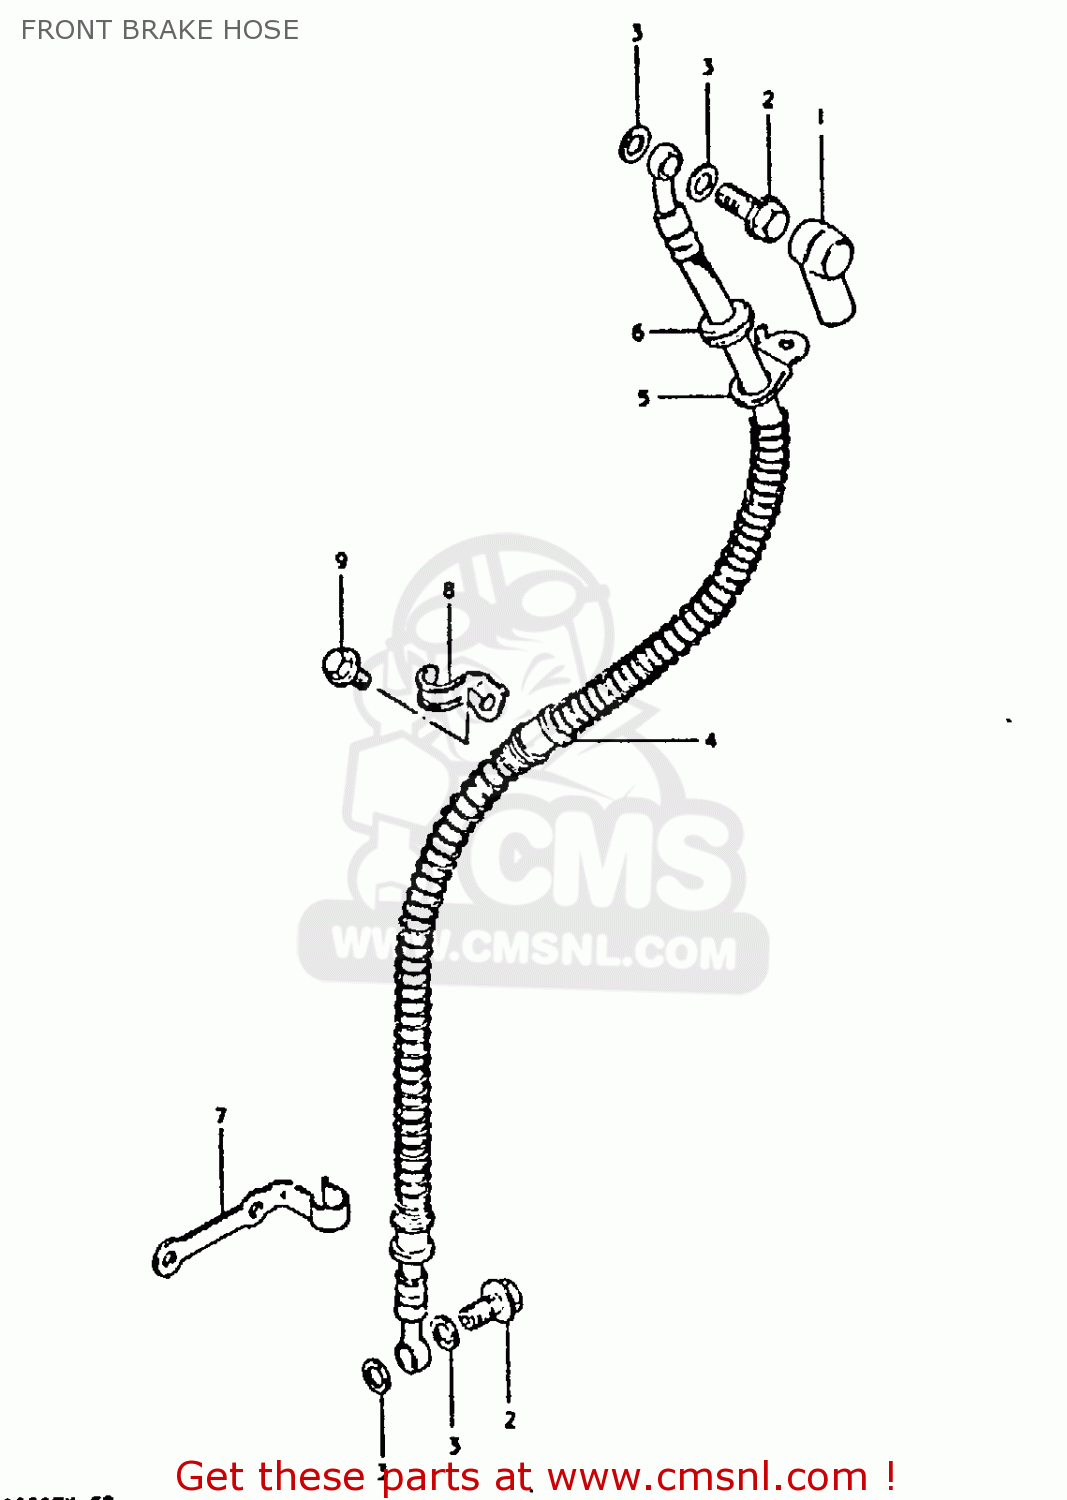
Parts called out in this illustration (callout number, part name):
1	BOOT,MASTER CYLINDER
2	BOLT,UNION
3	WASHER
4	HOSE,FRONT BRAKE
5	GUIDE,BRAKE HOSE
6	GROMMET
7	GUIDE,BRAKE HOSE NO.2
8	GUIDE,BRAKE HOSE NO.3
9	BOLT
